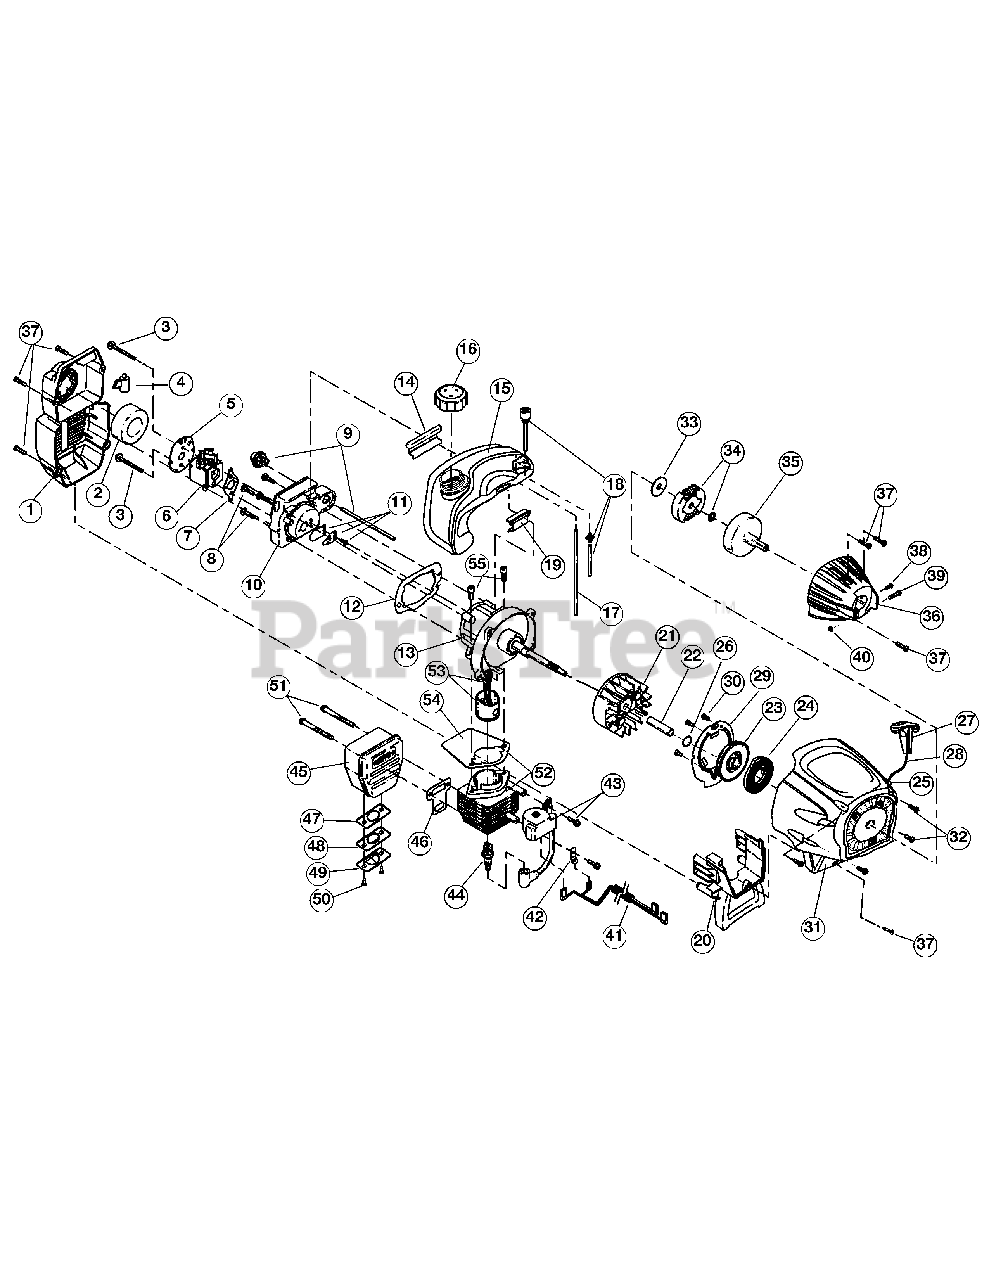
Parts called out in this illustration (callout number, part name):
1	Air Cleaner Cover Assembly (includes 2 & 37)
2	Air Cleaner Filter
3	Carburetor Mounting Screw Assembly
4	Choke Extension
5	Choke Plate
6	Carburetor Assembly (includes 7 & 18)
7	Carburetor Gasket
8	Carb Mount Screw
9	Primer & Hose Assembly
10	Carb Mount Assembly (includes 8, 11 & 12)
11	Reed Assembly
12	Carburetor Mount Gasket
13	Crankcase Service Assembly (includes 8)
14	Rear Mounting Pad
15	Fuel Tank Assembly (includes 16-18)
16	Fuel Cap Assembly
17	Fuel Return Line
18	Fuel Line Assembly
19	Front Mounting Pad
20	Shroud Extension & Stand
21	Flywheel Assembly
23	Recoil Pulley Assembly (includes 24, 26 & 28)
24	Recoil Spring
25	Rope Guide
26	Pulley Retainer
27	Pull Handle
29	Pressure Plate Assembly
30	Plate Screw
31	Starter Housing Assembly (includes 23-30, 32 & 37)
32	Housing Screw
33	Clutch Washer
34	Clutch Rotor Assembly
35	Clutch Drum Assembly
36	Clutch Cover Assembly (includes 37-40)
37	Cover Screw
38	Anti-Rotation Screw
39	Clamping Screw
40	Clamping Nut
41	Wire Leads and Sleeve
42	Ground Tab
43	Module Assembly (includes 42)
45	Muffler Assembly (includes 46-51)
46	Exhaust Gasket
47	Spark Arrestor Screen
48	Exhaust Hood Diverter
49	Exhaust Hood
50	Screws
51	Muffler Mounting Bolts
52	Cylinder Assembly (includes 54 & 55)
53	Piston and Rod Assembly
54	Cylinder Gasket
55	Cylinder Bolt
